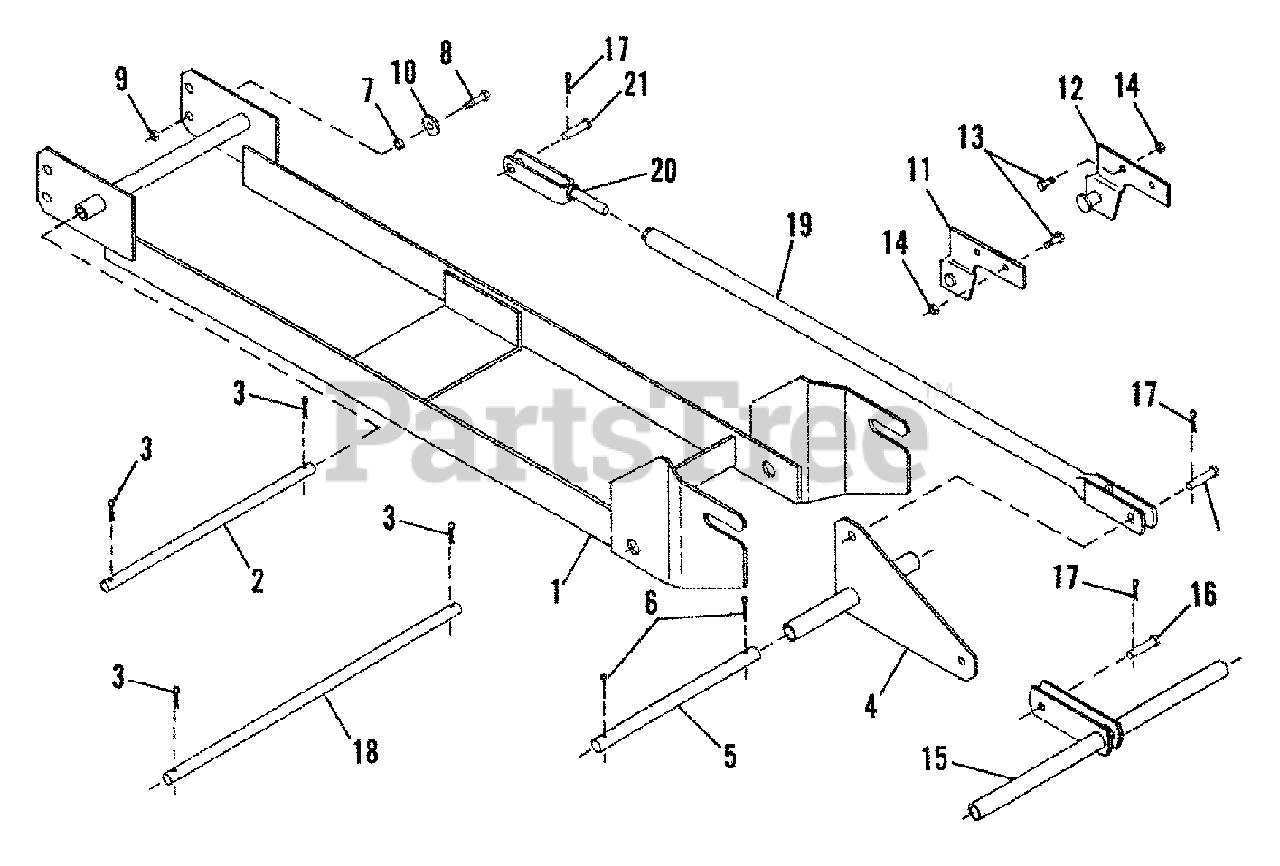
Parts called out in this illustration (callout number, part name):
1	Mounting Frame Assembly
2	Front Mounting Pin
3	Hair Cotter Pin
4	Lift Pivot Assembly
5	Lift Pivot Pin
6	Cotter Pin-3/16 x 1-3/4
8	Bolt-1/2-13 x 1-1/4 Hex Head
9	Nut-1/2-13 Hex Lock
10	Washer-9/16 x 1-3/8
11	LH Rear Mounting Bracket
12	RH Rear Mounting Bracket
13	Bolt-5/16-18 X 3/4 Hex
14	Nut-5/16-18 Hex Lock
15	Rear Lift Link Assembly
16	Clevis Pin
17	Hair Cotter Pin
18	Rear Lift Pin
19	Lift Tube Assembly
20	Adjusting Clevis
21	Clevis Pin
